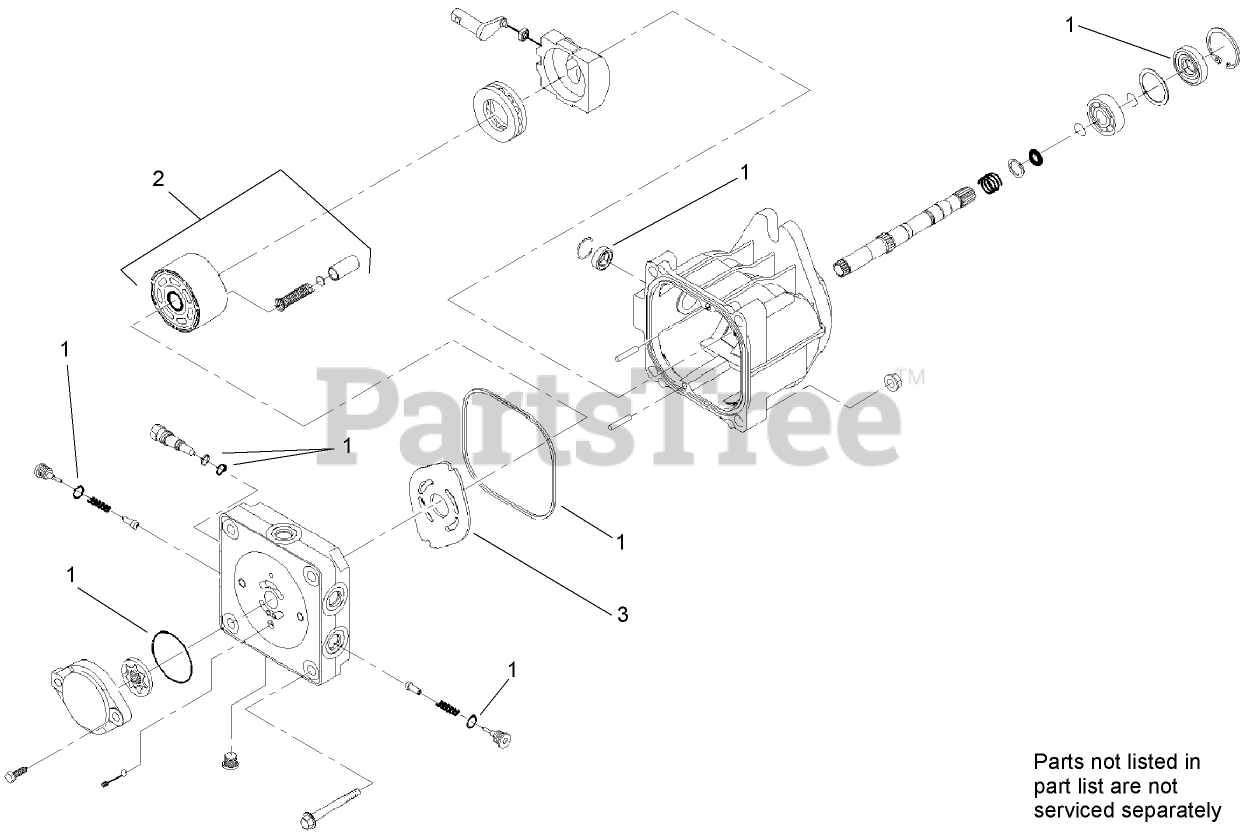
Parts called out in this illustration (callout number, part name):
1	OVERHAUL SEAL KIT
2	CYLINDER BLOCK ASM
3	PLATE-VALVE
